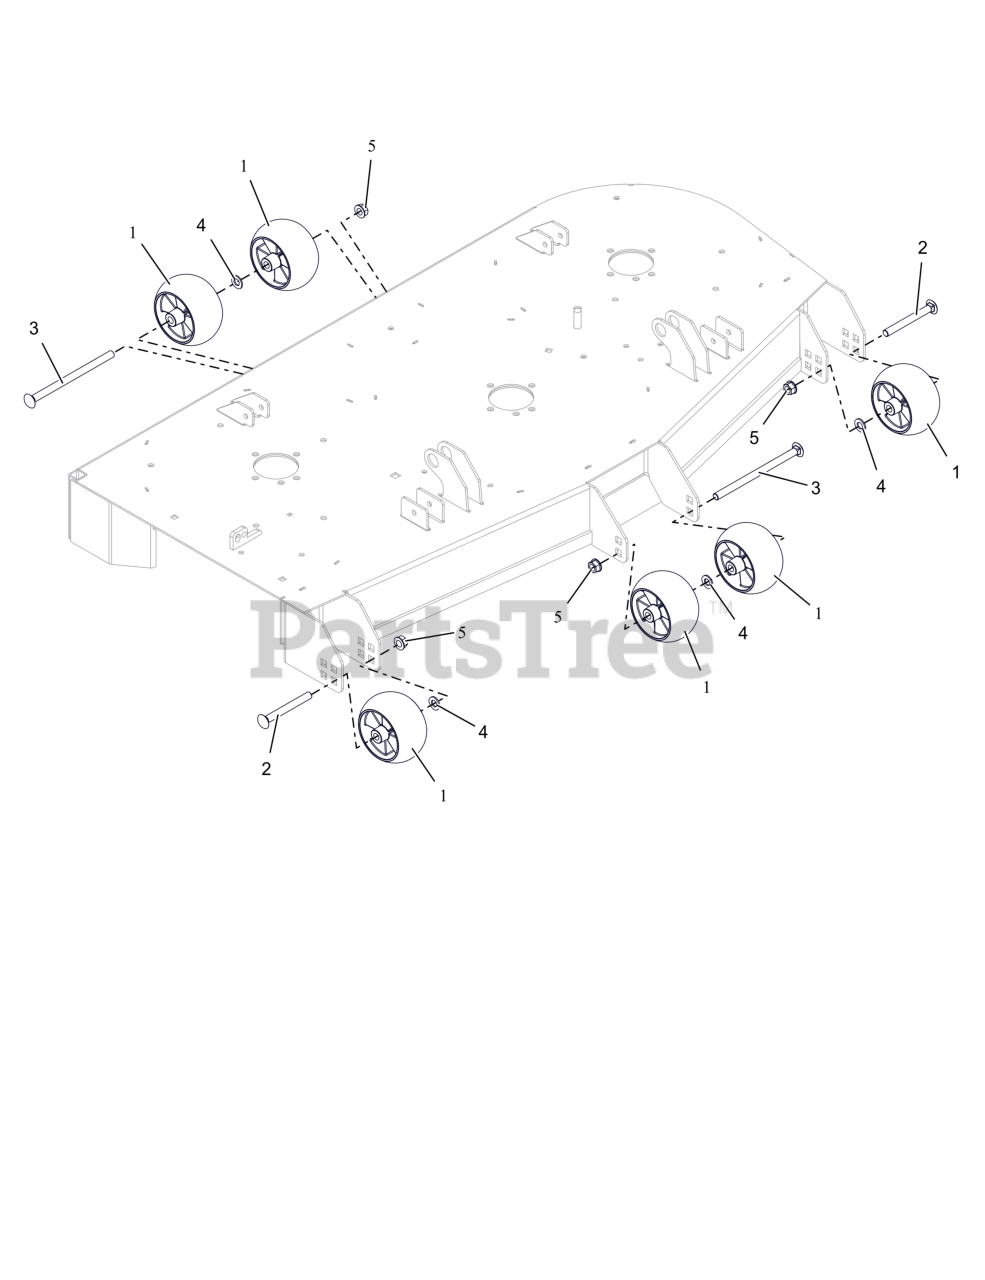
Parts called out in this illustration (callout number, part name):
1	WHEEL, ANTI SCALP - 5X3 CTR W/RIBS
2	BOLT, RHNS .50-13X4.50 G5 ZCC NS
3	BOLT, RHNS .50-13X8.00 G5 ZCC NS
4	WSHR,WAVE- TPE .525 X 1.00 X .090
5	NUT-LK-CTR-FLG .500-13 GG ZCC
